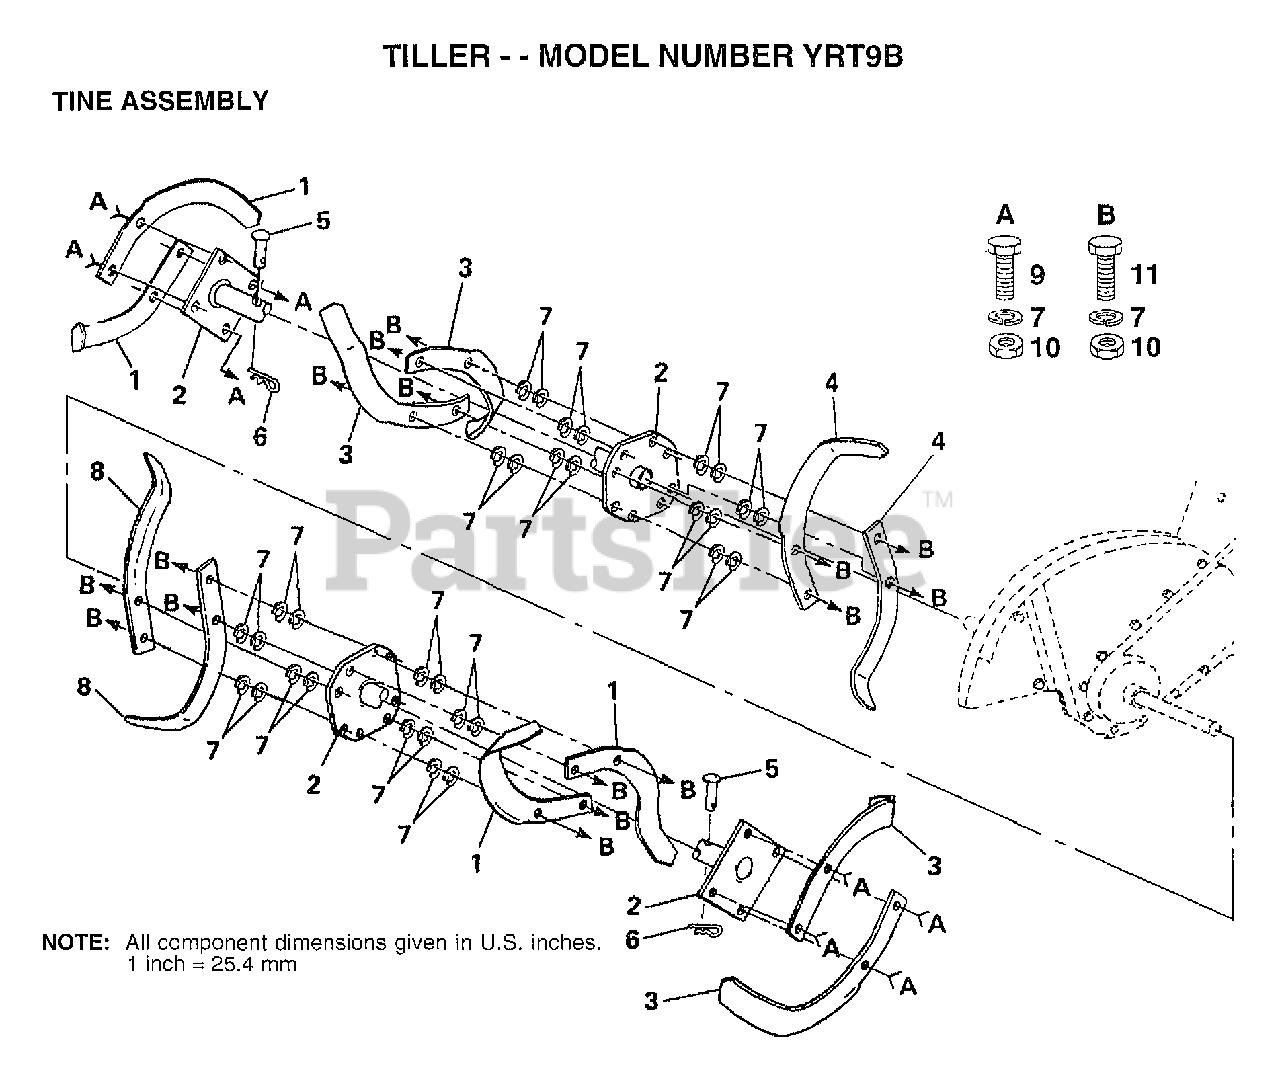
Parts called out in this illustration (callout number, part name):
2	TINE ASSY CRT
4	TINE.LH.CRT
5	RIVET.PAN HD.1.75
6	RETAINER.SPRING
7	LOCKWASHER
8	TINE RH CRT
9	BOLT
11	BOLT.3/8-24X1-1/2
